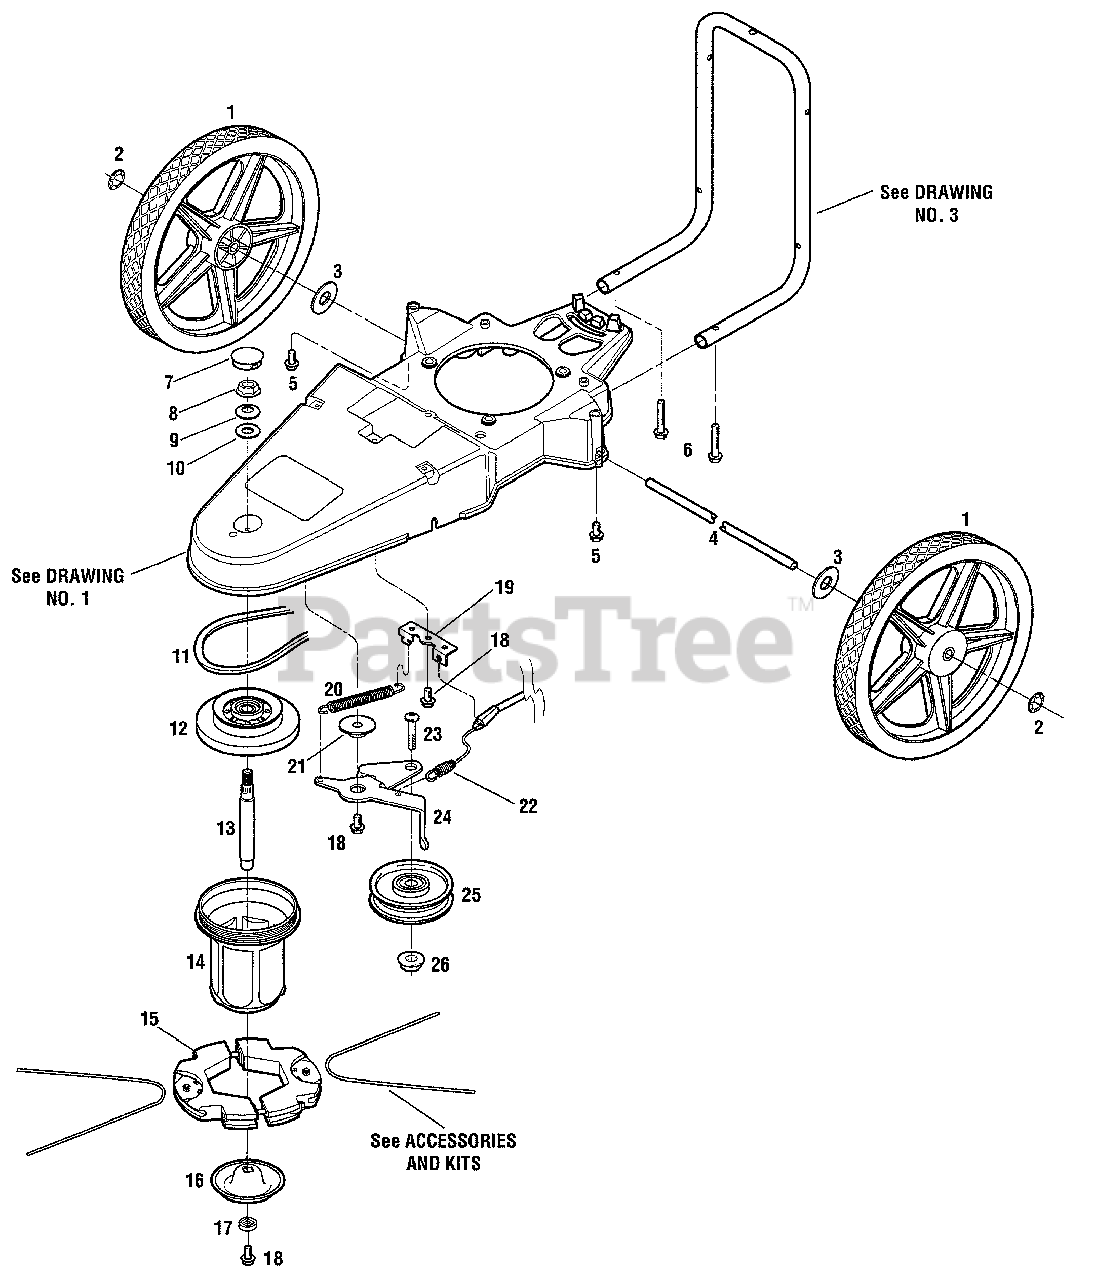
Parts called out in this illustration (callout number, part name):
1	Wheel/Tire Assembly
2	Locking Retaining Ring
3	Flat Washer
5	Self-Tap Screw, 5/16-18 x 3/4
6	Self-Tap Screw, 5/16-18 x 2
7	Cap Plug
8	Flange Lock Nut, 1/2-13
9	Belleville Washer
10	Hardened Washer
12	Spindle Head Adapter
13	Spindle Shaft
14	Spindle Head Assembly
15	Trimmer Head Assembly
16	Wear Cup
17	Square Washer
18	Self-Tap Screw, 5/16-18 x 3/4
19	Cable Bracket
20	Idler Spring
21	Flat Washer
22	Control Cable-Trimmer Head
23	Button Hd. Screw, 3/8-16 x 1-1/2
24	Idler Arm
25	Idler Pulley
26	Flange Lock Nut, 3/8-16
